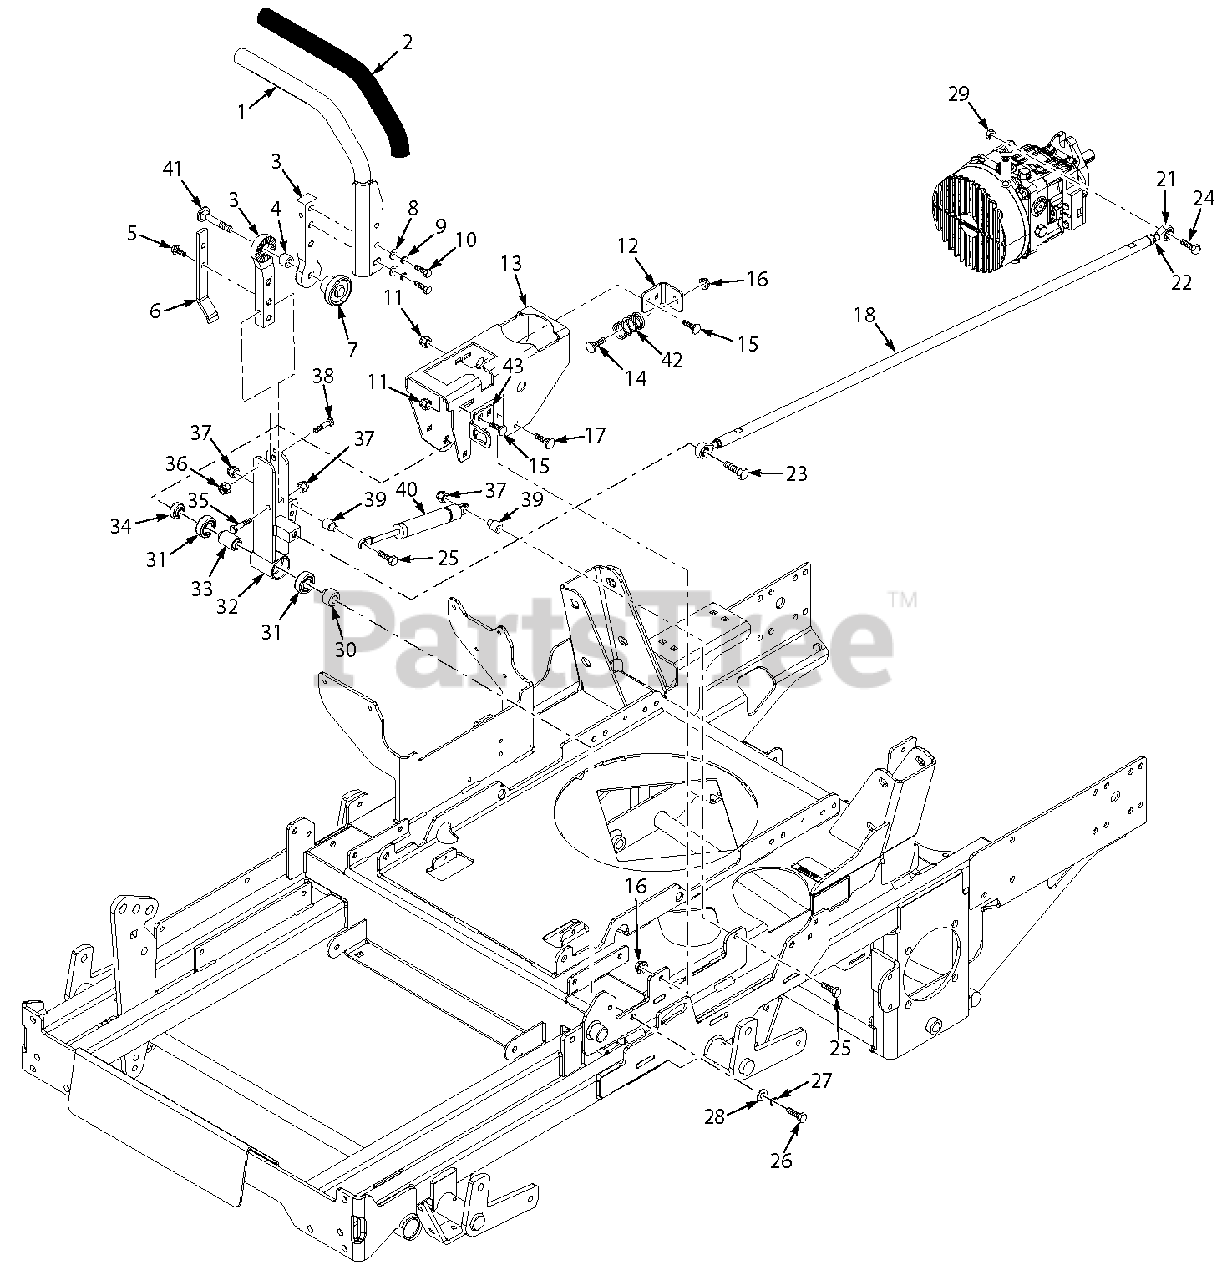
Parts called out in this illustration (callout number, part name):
1	Handle Bar w/Grip - LH
1	Handle Bar w/Grip - RH
2	Grip, Control Lever
3	Pivot, Control Lever
4	Spacer, Rubber
5	Bolt, Hex Head Serrated Flange 5/16-18 x 3/4"
6	Actuator, Switch
7	Knob, Control Handle
8	Flatwasher, 3/8-.391 x .938 x .105
9	Lockwasher, 3/8
10	Bolt, Hex Head 3/8-16 x 1"
11	Nut, Flange Elastic Stop 1/4-20
12	Mounting Bracket, Spring Return
13	Mounting Weldment, LH Control
13	Mounting Weldment, RH Control
14	Bolt, Carriage 5/16-18 x 3/4"
15	Bolt, Carriage 1/4-20 3/4"
16	Nut, Serrated Flange 5/16-18
17	Bolt, Carriage 5/16-18 x 3/4"
18	Linkage Assy., Pump Control
19	Rod End, Male - LH
20	Nut, 3/8-24 UNF LH Jam
21	Rod End, Male - RH
22	Nut, 3/8-24 UNF Jam
23	Bolt, Hex Head 3/8-16 x 1-1/2"
24	Bolt, Hex Head 3/8-16 x 1-1/4"
25	Bolt, Hex Head 5/16-18 x 1-1/2"
26	Bolt, Hex Head 3/8-16 x 4-1/4"
27	Lockwasher, 3/8"
28	Flatwasher, 3/8-.391 x .938 x .105
29	Nut, Center Lock 3/8-16
30	Spacer, Controls
31	Bearing
32	Control Lever Weldment, RH
32	Control Lever Weldment, LH
33	Spacer, Bearing
34	Spacer, Controls
35	Bolt, Hex Head 5/16/-18 x 2"
36	Nut, Elastic Stop 3/8-16
37	Nut, Elastic Stop 5/16-18
38	Bolt, Hex Head 3/8-16 x 2"
39	Spacer, Dampener
40	Dampener
41	Bolt, Carriage 3/8-16 x 1-1/2"
42	Return Spring, Control Arm
43	Mounting Bracket, Brake Switch
